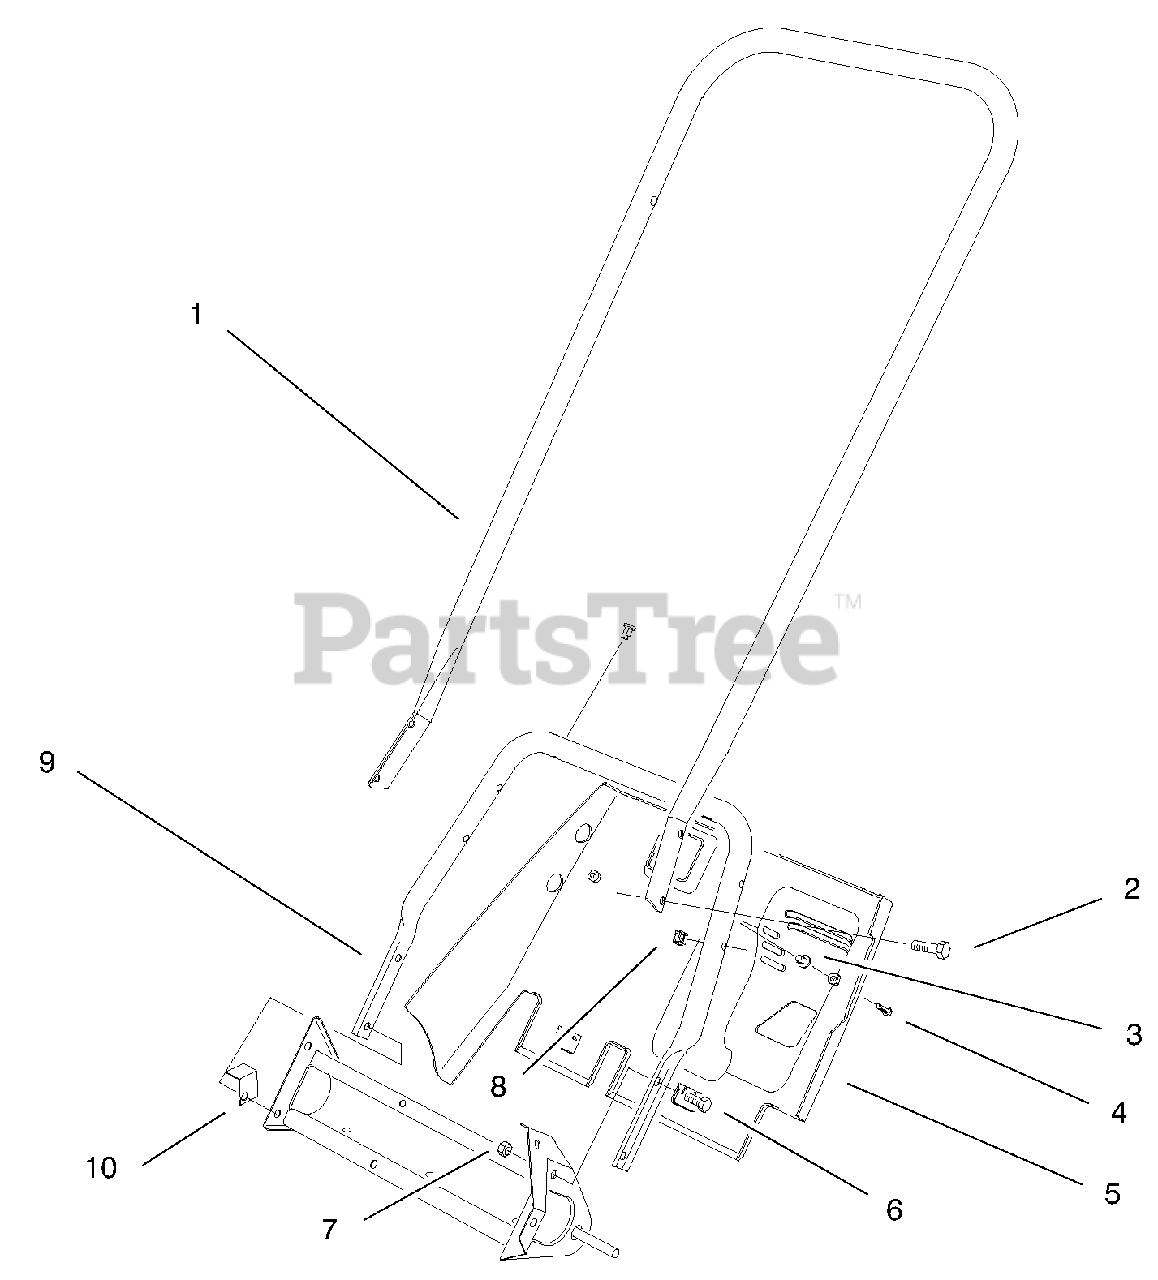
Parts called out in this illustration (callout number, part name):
1	Handle-Upper
2	Screw-Hex. Hd.
4	Screw-Thread Forming
5	Shroud-Lower
6	Screw-Hex. Hd.
7	Nut-Lock
8	Nut-Speed
9	Handle-Lower
10	Bracket-Shroud
